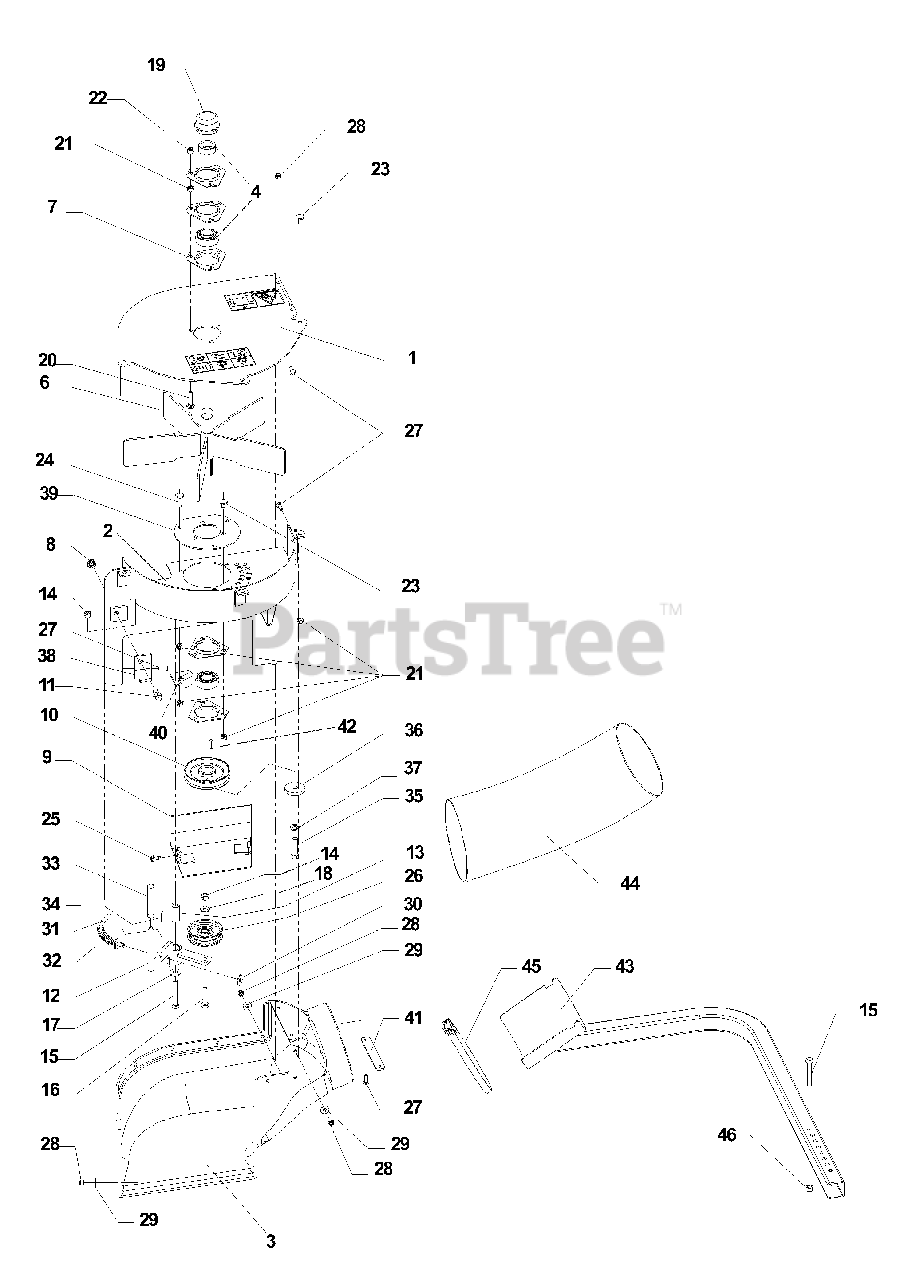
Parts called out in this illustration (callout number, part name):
1	FAN COVER W/DECALS
2	UPPER HOUSING
3	LOWER HOUSING
4	BEARING WITH COLLAR
6	FAN WLDMT.
8	NUT, 3/8-16, FLANGE
9	SHEAVE FLOOR
10	SHEAVE, 4"
11	BOLT, 3/8-16 X 1
13	SLEEVE BUSHING
14	NUT, 3/8-16, CTR. LOCK
15	BOLT, 3/8-16 X 2 1/4
16	BOLT, 3/8-16 X 1 1/2
17	WASHER, 3/8
18	WASHER, 3/8, SAE
19	GREASE CAP
20	BOLT, 5/16-18 X 1 1/4, CARRIAGE
21	NUT, 5/16-18, CTR. LOCK
22	NUT, 5/16-18, NYLOC
23	BOLT, 5/16-18 X 5/8, CARRIAGE
24	BOLT, 5/16-18 X 1
25	SCREW, 1/4-20 X 5/8, SELF TAP
27	BOLT, 1/4-20 X 3/4, CARRIAGE
28	NUT, 1/4-20, NYLOC
29	WASHER, 1/4
30	WASHER, 5/16
31	SPRING ROD
33	VINYL GRIP
34	COTTER PIN 3/32 X 3/4
35	BOLT, 7/16-20 X 1 1/2
36	HEAVY WASHER
37	LOCKWASHER, 7/16
39	BEARING PLATE
40	BELT GUIDE
42	KEY 1/4 X 3/4 SQ.
45	HOSE CLAMP
46	NUT, 3/8-16, NYLOC
